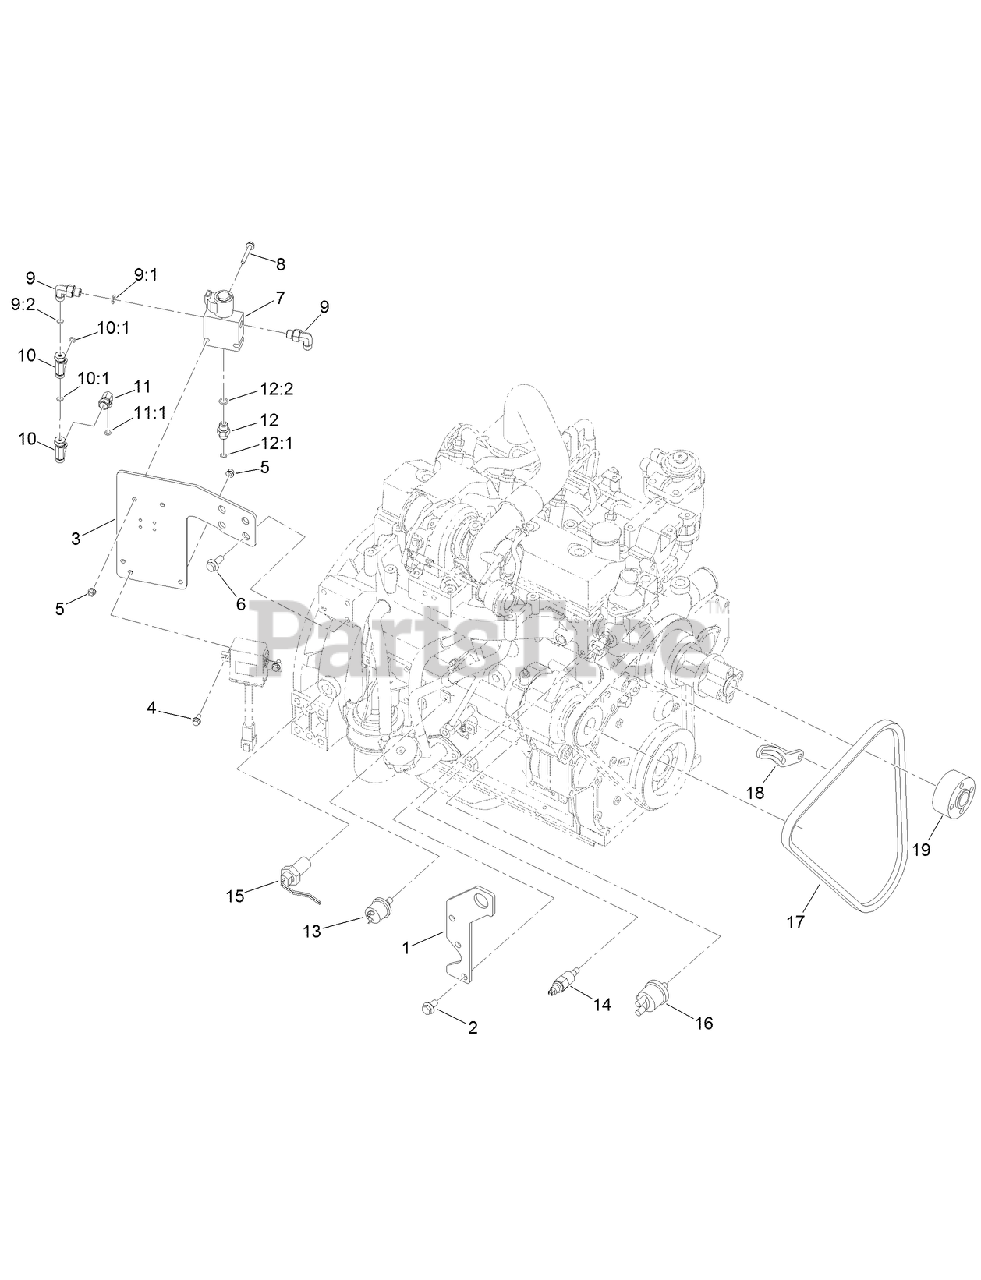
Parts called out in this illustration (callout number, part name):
1	PLATE-POINT, HOIST
2	SCREW-HHF
3	PLATE-MOUNT
4	SCREW-HHF
5	NUT-FLANGE, NI
6	SCREW-HHF
7	VALVE-SOLENOID
8	SCREW-HHF
9	FITTING-ELBOW 90
9:1	O-RING
9:2	O-RING
10	FITTING-HYD
10:1	O-Ring
11	FITTING-ADAPTOR
11:1	O-RING
12	FITTING-STRAIGHT
12:1	O-RING
12:2	O-RING
13	SENSOR-PRESSURE, OIL
14	SENSOR-COOLANT
15	SENSOR-RPM, MAG PICKUP
16	SENSOR-PRESSURE, OIL
17	BELT-V
18	BRACKET-ALTERNATOR
19	SPACER-FAN
